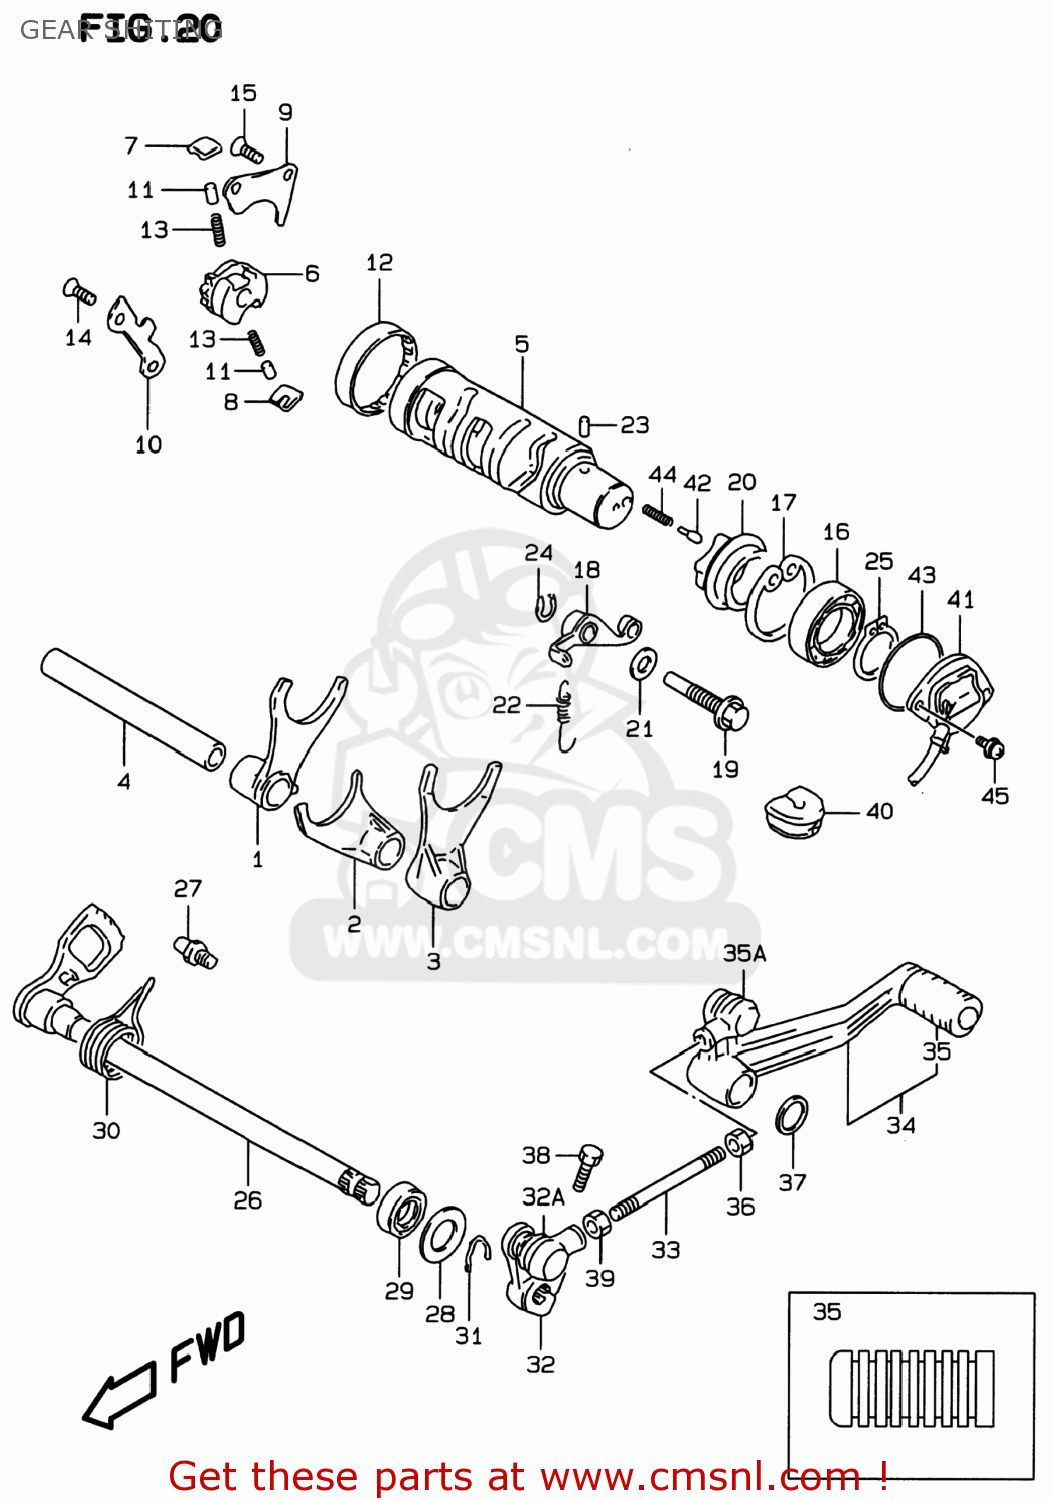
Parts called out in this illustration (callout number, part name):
1	FORK,GEAR SHIFT NO.1
2	FORK,GEAR SHIFT NO.2
3	FORK,GEAR SHIFT NO.3
4	SHAFT,GEAR SHIFT FORK(L:128)
5	CAM,GEAR SHIFT
6	GEAR,GEARSHIFT CAM DRIVE
7	PAWL,GEAR SHIFT NO.1
8	PAWL,GEAR SHIFT NO.2
9	LIFTER,GEAR SHIFT PAWL
10	GUIDE,GEAR SHIFT CAM
11	PIN(5X8)
12	BEARING(43X49X12)
13	SPRING
14	SCREW
15	SCREW
16	BEARING
17	CIRCLIP
18	STOPPER,GEAR SHIFT CAM
19	SHAFT,GEAR SHIFT CAM STOPPER
20	PLATE,STOPPER
21	GASKET(10X14X3.6) (NAS)
22	SPRING
23	PIN
24	CIRCLIP
25	CIRCLIP
26	SHAFT,GEAR SHIFT
27	STOPPER,GEAR SHIFT CAM
28	WASHER (12.5X27X1.6)
29	OIL SEAL
30	SPRING
31	CIRCLIP,12 MM
32	ARM,GEAR SHIFT LINK
32A	COVER,DUST
33	ROD,GEAR SHIFT LINK
34	LEVER ASSY,GEAR SHIFT
35	RUBBER,GEAR SHIFT PEDAL
35A	COVER,DUST
36	NUT
37	WASHER(18X24X1)
38	BOLT
39	NUT
40	GROMMET,LEADWIRE
41	TERMINAL BASE ASSY,NEUTRAL
42	PIN(5X15.5)
43	O RING(D:2.4,ID:35.5)
44	SPRING
45	SCREW
